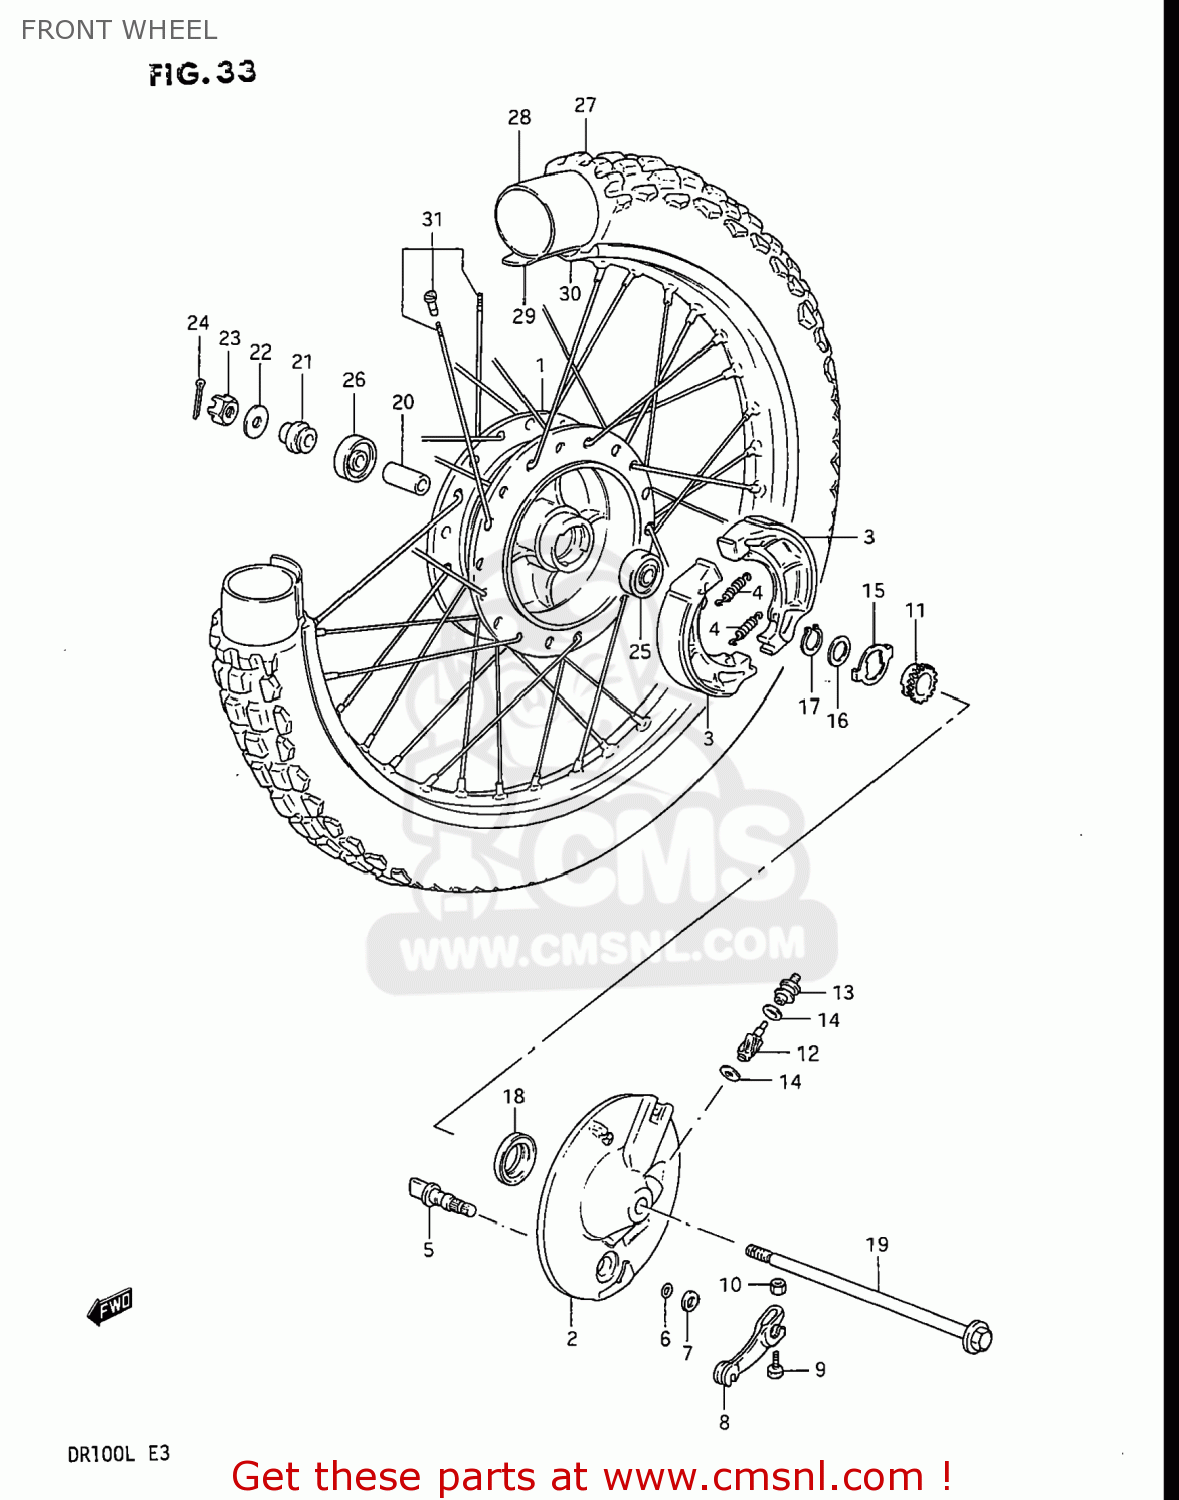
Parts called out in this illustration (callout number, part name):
1	HUB,FRONT
2	PANEL,FRONT HUB
3	SHOE,BRAKE
4	SPRING(L:34)
5	CAM,FRONT BRAKE
6	O-RING (D:2.4 ID:13.8)
7	WASHER (14.5X22X1.6)
8	LEVER,FR BRAKE CAM
9	BOLT 6X35
10	NUT
11	GEAR,SPEEDOMETER
12	PINION,SPEEDOMETER(NT:9)
13	BUSH,SPEEDOMETER PINION OUTER
14	WASHER (5.1X9X0.4)
15	DRIVER,SPEEDOMETER GEAR
16	WASHER(18.5X24X1)
17	CIRCLIP
18	OIL SEAL (43X58X7)
19	AXLE,FRONT
20	SPACER (12.6X19X52)
21	SPACER,FRONT AXLE,RIGHT
22	WASHER
23	NUT 12MM
24	COTTER PIN
25	BEARING
26	BEARING (12X32X10)
27	TIRE 2.75-17
28	TUBE,INNER
29	PROTECTOR,WHEEL,INNER
30	RIM,FRONT WHEEL
31	SPOKE SET,FRONT
